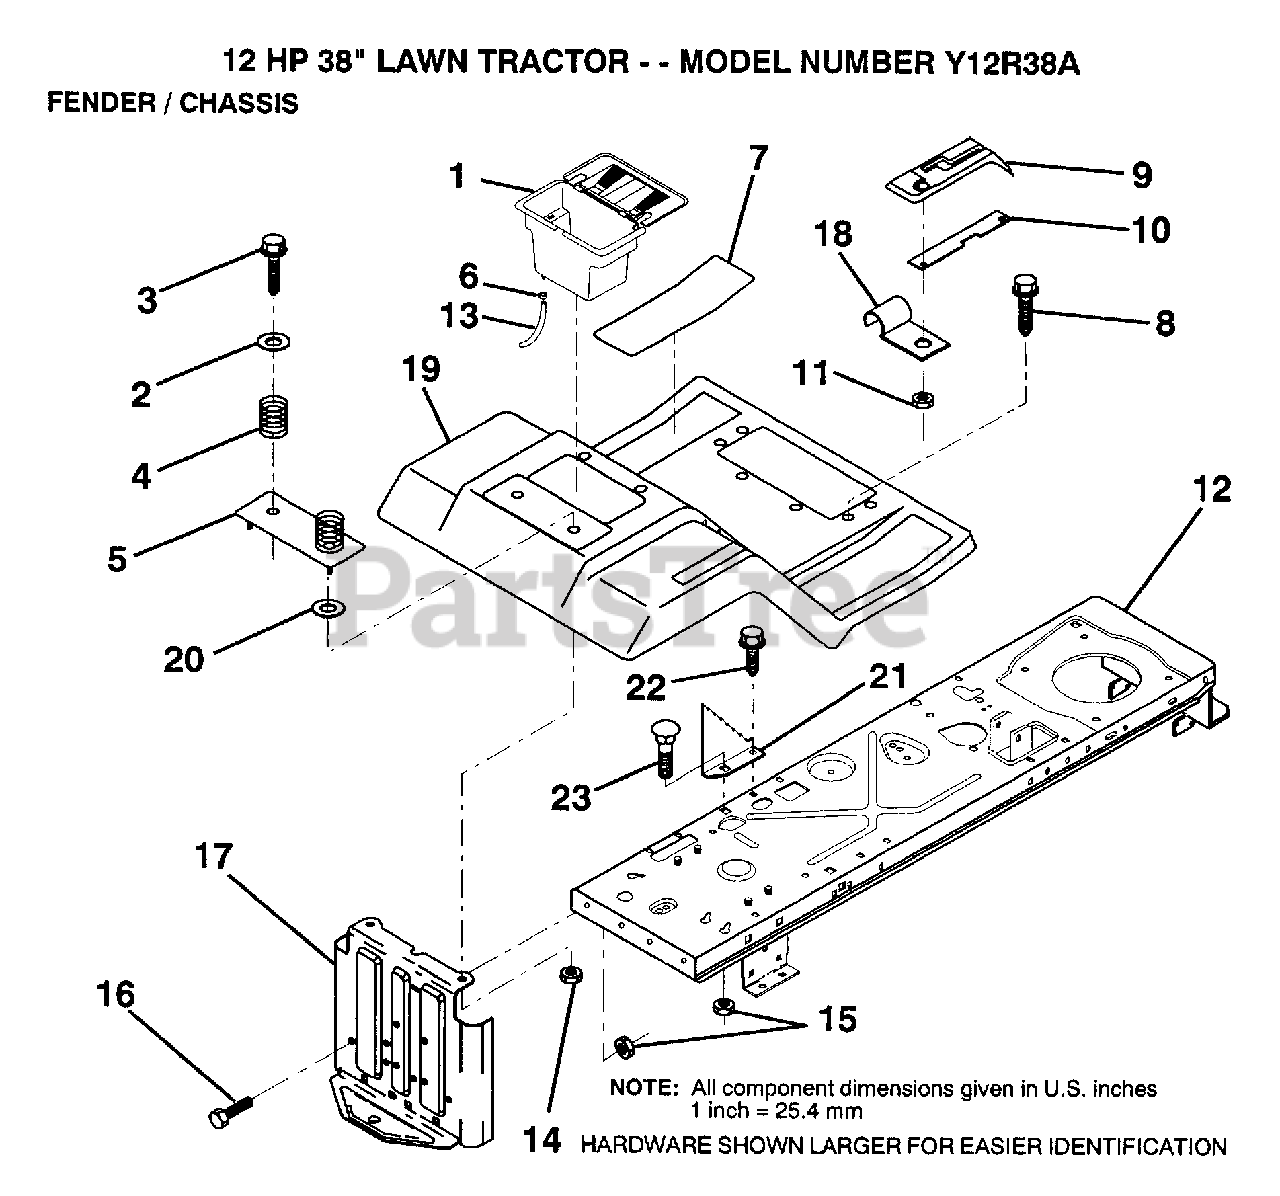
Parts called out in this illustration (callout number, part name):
2	WASHER
3	SCREW
4	SPRING COMPRESSIO
5	BTRY FENDER PLATE
6	HOSE CLAMP T
7	PAD FOOTREST
8	SCREW
10	"SHIFT LOCK, BAR"
11	NUT
14	NUT
16	BOLT
17	DRAWBAR
18	"CLIP,INSULATOR"
22	SCREW LT
